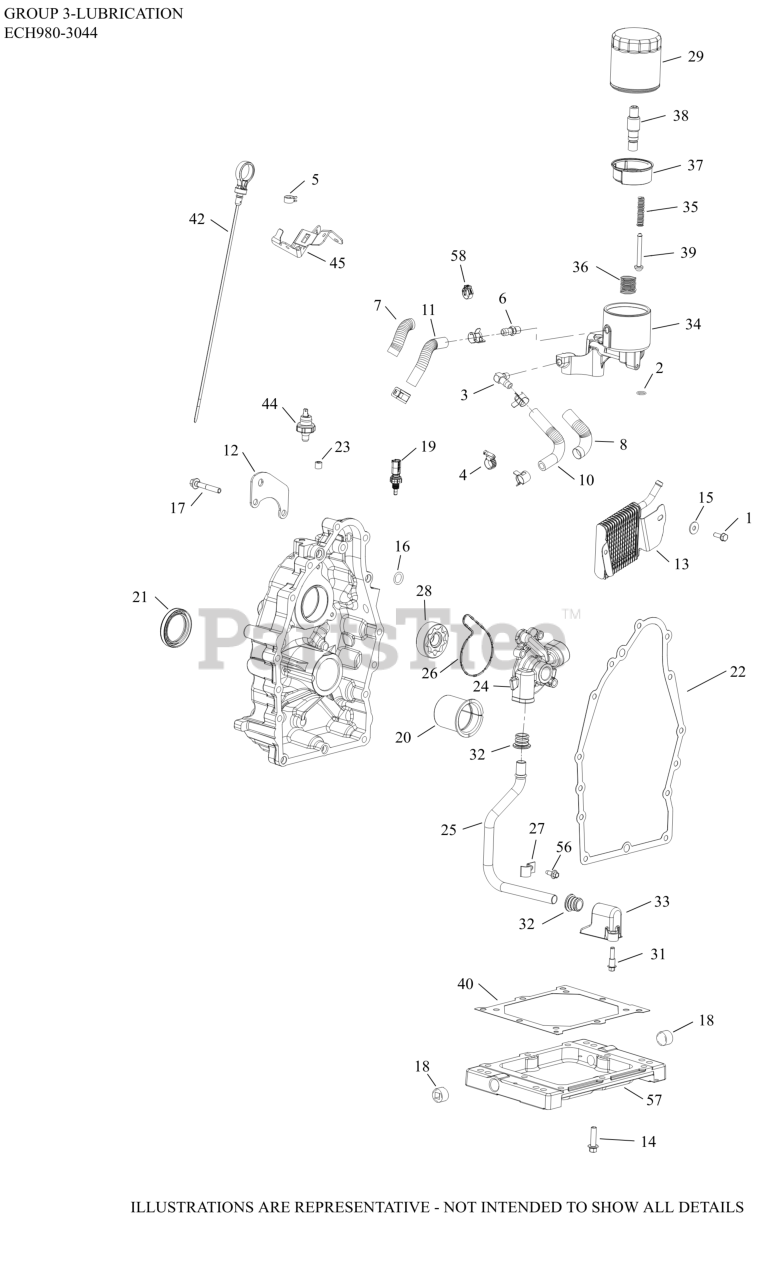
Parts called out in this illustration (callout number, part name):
1	SCREW, TAP M6X1.7X18
2	O-RING, OIL PICK-UP
3	CONNECTOR, HOSE
5	SPRING CLAMP, HOSE
6	FITTING, BARBED HOSE
7	SLEEVE, ANTI ABRASION-USE 25 431 12-S
8	SLEEVE, ANTI ABRASION-USE 25 431 12-S
9	KIT, CLOSURE PLATE-(#6200922S)
10	HOSE, OIL SUPPLY
11	HOSE, OIL RETURN
12	STRAP, LIFTING
13	COOLER, OIL ASSEMBLY
14	SCREW, FLG M8X1.25X30
15	WASHER, FLAT 1/4"
17	SCREW, HEX FLANGE
18	PLUG, PIPE 1/2 NPTF SQ CTSK
19	SENSOR, TEMPERATURE
20	BEARING, CRANKSHAFT (PTO)
21	SEAL, OIL
22	GASKET, OIL PAN
23	PLUG, CTSK PIPE 1/8"
24	HOUSING, OIL PUMP MACH-USE 62 081 38-S
25	TUBE, OIL PICK-UP
26	O-RING, OIL PUMP HOUSING
28	PUMP ASSEMBLY, OIL/GEROTOR
29	OIL FILTER
31	SCREW, SHD THD FRM M6X.0X6.5
32	SEAL, PICK-UP TUBE
33	HOUSING, OIL PICK-UP ASSEMBLY
34	KIT, OIL FILTER HOUSING
35	SPRING, OIL FILTER VALVE
36	SPRING, OIL FILTER CUP
37	CUP, OIL FILTER ASSEMBLY
38	NIPPLE, OIL FILTER ASSEMBLY-(#6213606S)
39	VALVE, OIL FILTER
40	GASKET, OIL RESERVOIR
44	SWITCH, OIL PRESSURE
45	BRACKET, FUSE HOLDER
56	SCREW, THREAD FORMING
57	OIL RESERVOIR
58	CLAMP, HOSE OETIKER
65	SCREW, HEX FLANGE M6 X 1
